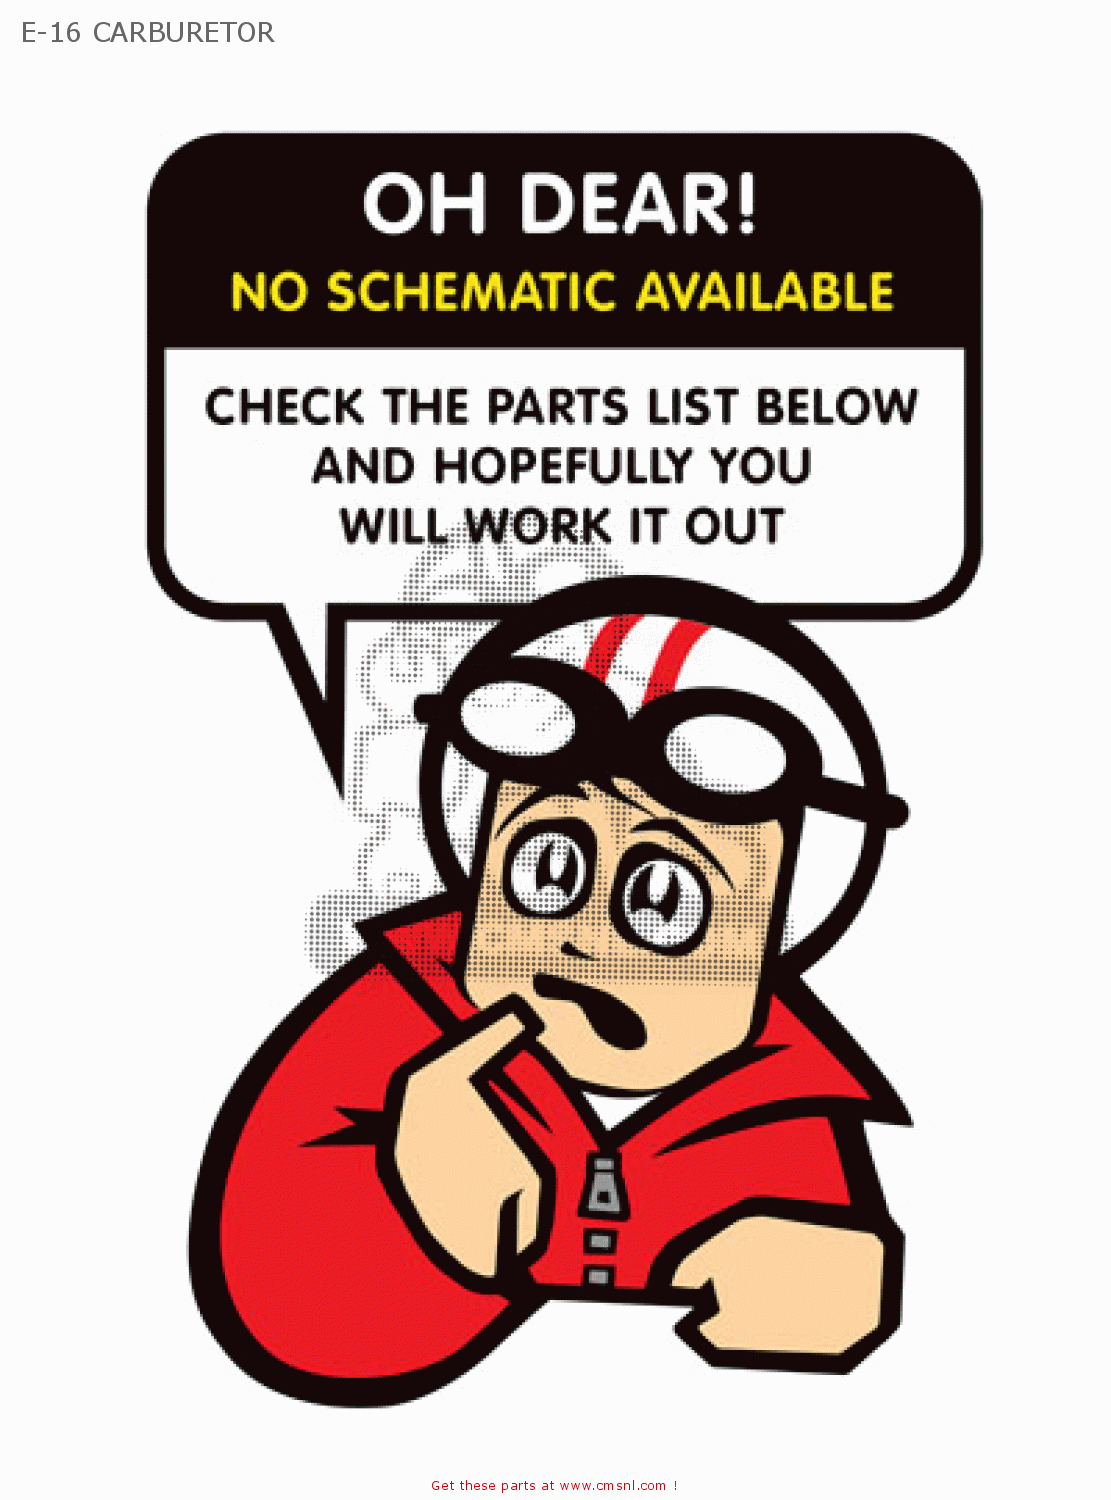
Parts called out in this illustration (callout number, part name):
1	MUFFLER ASSEMBLY
2	O-RING (D:3.5 ID:54.4)
3	TUBE,MUFFLER CLEAN OUT
4	COVER,SECOND MUFFLER TAIL
5	SCREW(6X8)
6	WASHER,LOCK
7	WASHER
8	COVER AIR CLEANER
9	FLANGE,EXHAUST PIPE
10	BODY,MUFFLER
11	CLAMP
12	CLAMP
13	SCREW
14	SPACER
15	GASKET
16	JET,MAIN(290)
17	SPRING
